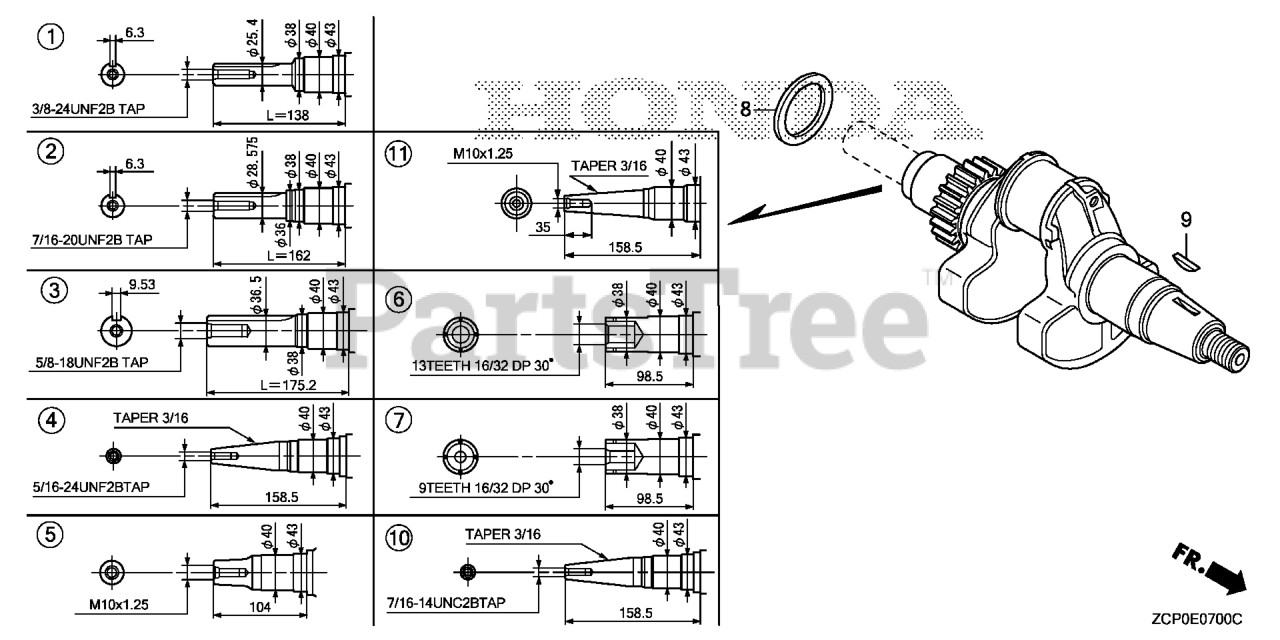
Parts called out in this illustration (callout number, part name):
1	CRANKSHAFT (L=138)
8	WASHER, CRANKSHAFT THRUST
9	KEY, SPECIAL WOODRUFF (25X18)
